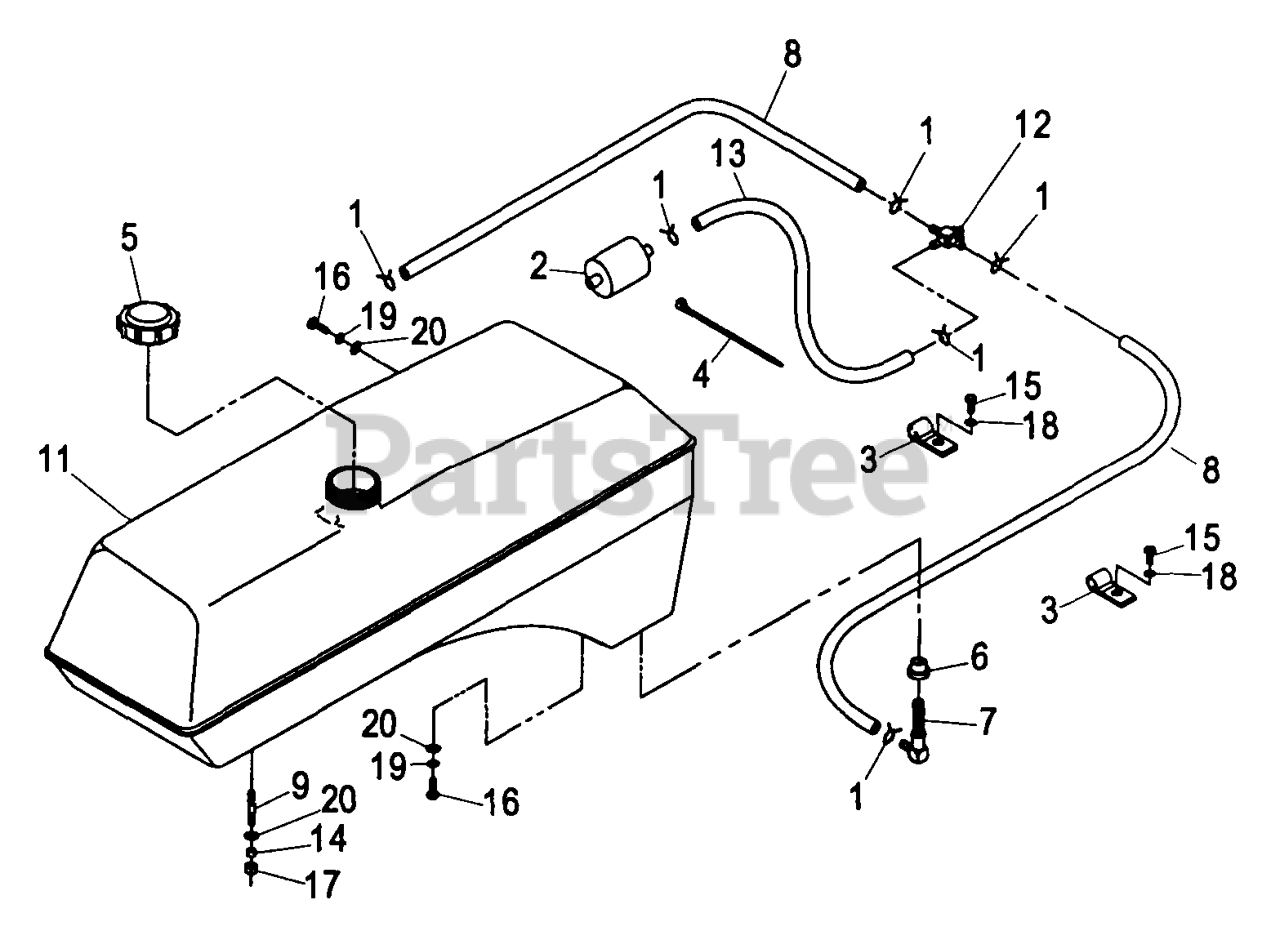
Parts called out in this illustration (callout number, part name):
2	Fuel Filter
3	CLIP-LOOM
4	TIE-PLASTIC
5	CAP-FUEL
7	ELBOW-TANK, FUEL
8	HOSE-FUEL
9	STUD
12	VALVE-FUEL
14	SPRING-TANK, FUEL
18	WASHER-LOCK
19	WASHER-LOCK
